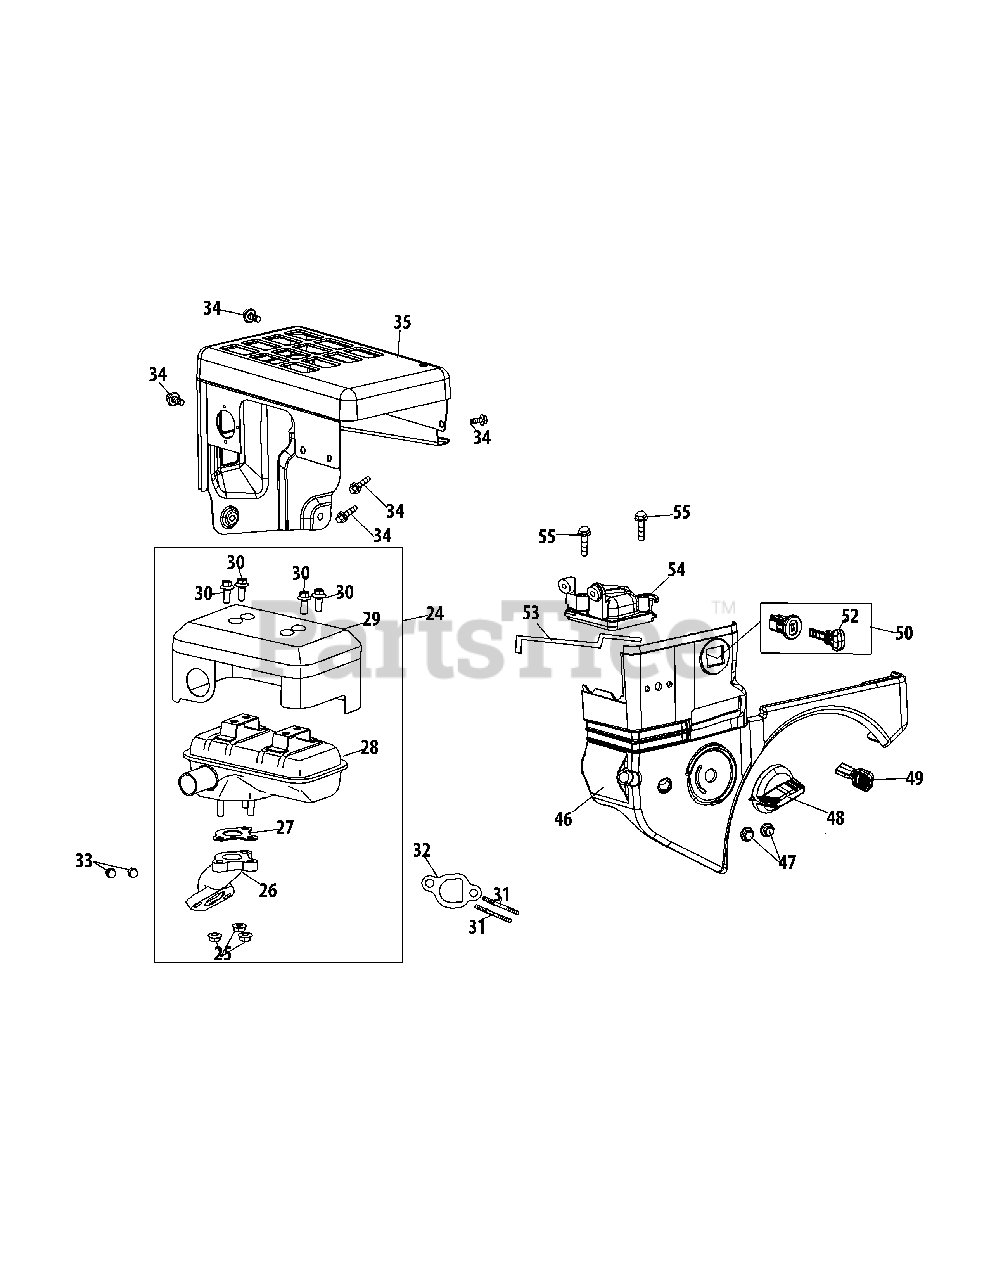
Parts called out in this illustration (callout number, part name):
24	Muffler Assembly
25	Flange Nut M6
26	Exhaust Pipe
27	Gasket, Muffler
28	Muffler Body
29	Muffler Guard
30	Bolt M5×10/Stainless Steel
31	Stud M8×36
31	Muffler Stud Assembly
32	Exhaust Pipe Gasket
34	Bolt M6×12
35	Muffler Shield
46	Air Cleaner Housing
48	Choke Knob
49	Throttle Control Knob
50	Key Switch Assembly
53	Choke Linkage
54	Heater Box
55	Bolt M6×28
